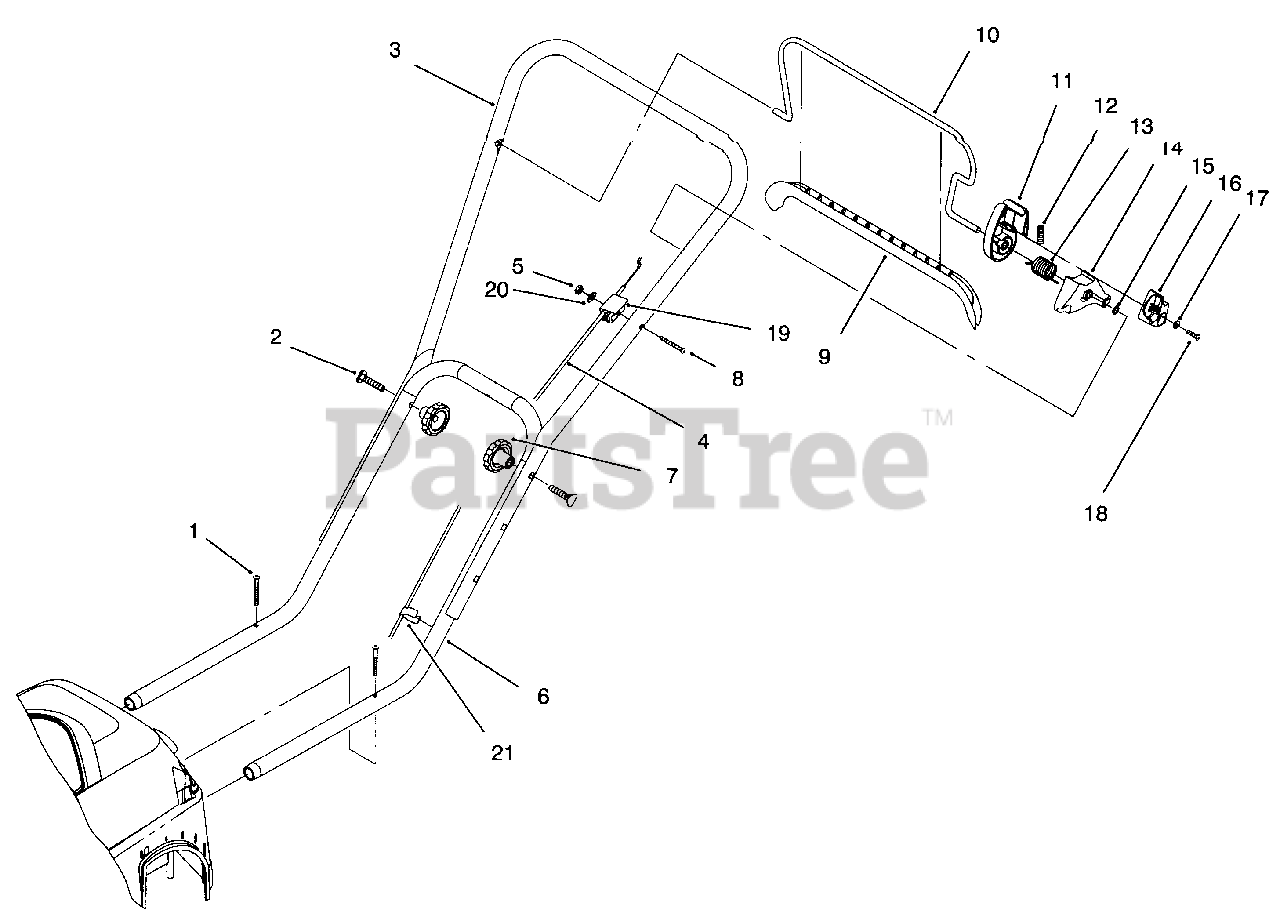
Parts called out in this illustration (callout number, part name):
1	Screw-PPH
2	Screw-Handle
3	Handle-Upper
4	Cable Control
5	Nut-Lock
6	Handle-Lower
8	Screw-HH
9	Cover-Bail
11	Housing-Bail
12	Spring-Slide
13	Spring-Bail
15	Nut-Push
17	Washer-Flat
18	Screw-PH
19	Support-Cable
20	Washer-Flat
21	Clip-Cable
